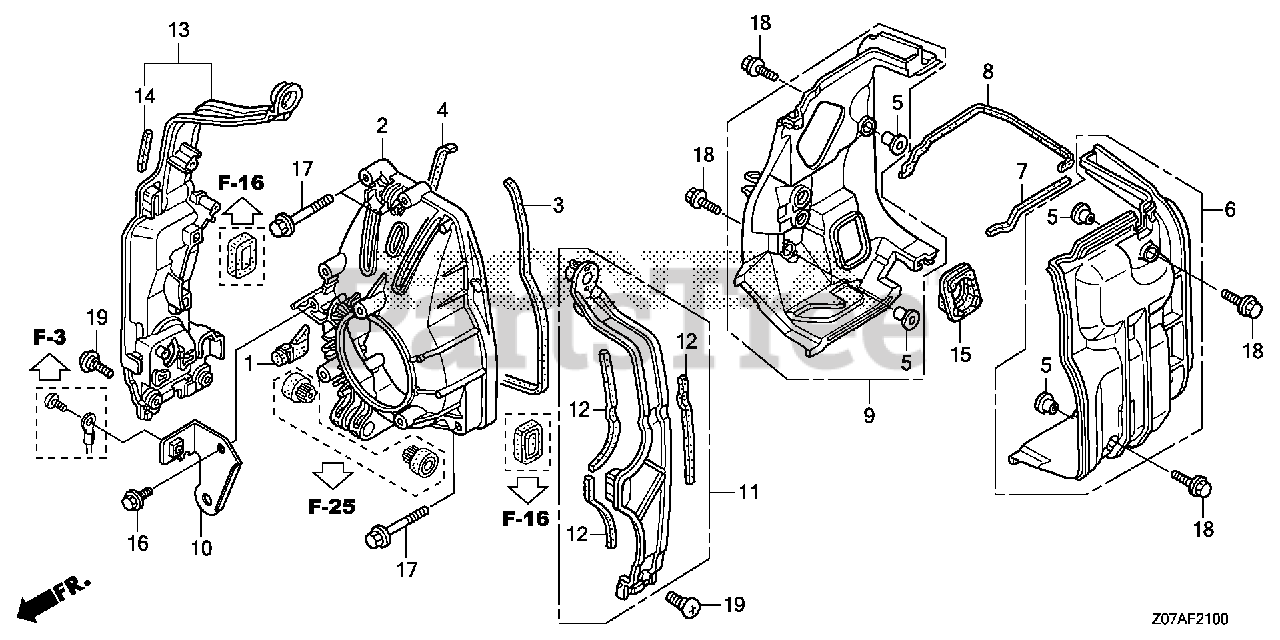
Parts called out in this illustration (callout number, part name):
1	RUBBER, TANK PROTECTOR
2	COVER, FAN
3	SEAL, R. FAN COVER (L. SIDE)
4	SEAL, L. FAN COVER (R. SIDE)
5	COLLAR, FAN COVER
6	SHROUD, R. (L. SIDE)
7	SEAL, R. SHROUD (UPPER) (L. SIDE)
8	SEAL, L. SHROUD (UPPER) (R. SIDE)
9	SHROUD, L. (R. SIDE)
10	BRACKET, TERMINAL
11	FRAME ASSY., R. FR. (L. SIDE)
12	SEAL, R. FR. FRAME (L. SIDE)
13	FRAME ASSY., L. FR. (R. SIDE)
14	SEAL, L. FR. FRAME (R. SIDE)
15	RUBBER, OIL CHECK
16	BOLT, FLANGE (6X14) (CT200)
17	BOLT, FLANGE (6X45) (CT200)
18	BOLT, FLANGE (6X23) (CT200)
19	SCREW, SPECIAL (6X15)
